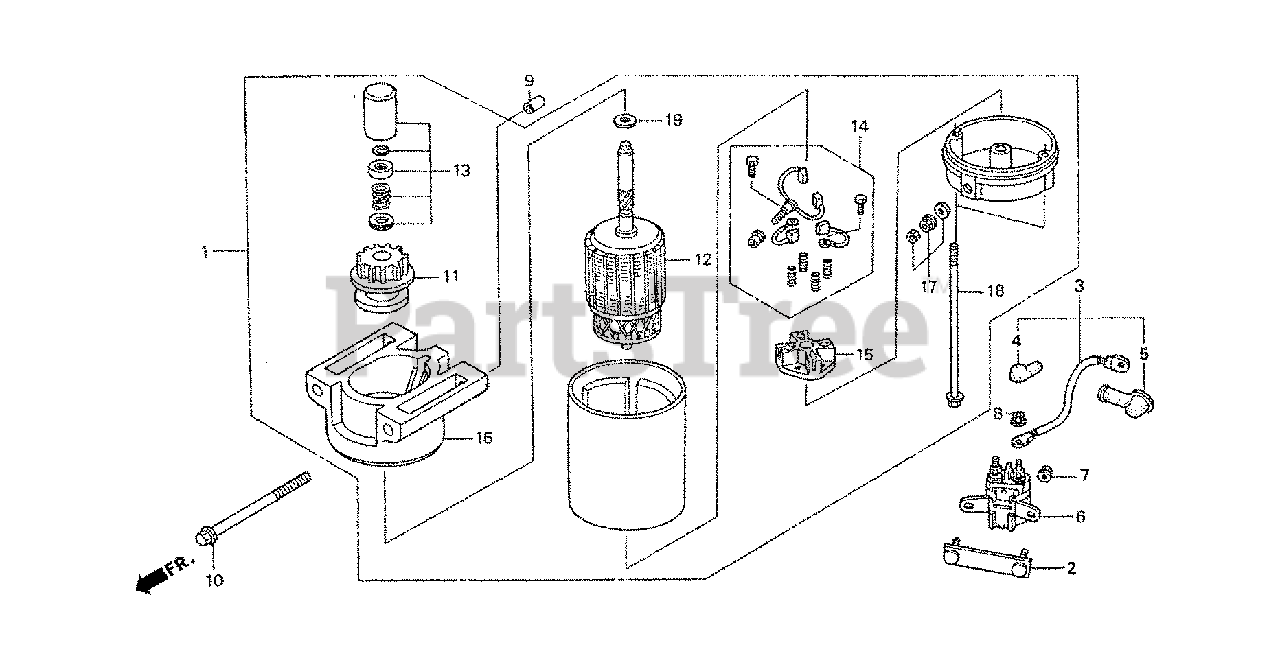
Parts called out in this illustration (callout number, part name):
1	MOTOR ASSY., STARTER
2	BRACKET, STARTER MAGNETIC SETTING
3	CABLE, MAGNET SWITCH
4	COVER A, MAGNETIC SWITCH
5	COVER, STARTER MOTOR TERMINAL
6	SWITCH ASSY., STARTER MAGNETIC
7	NUT, FLANGE (6MM)
8	NUT-WASHER (6MM)
9	PIN, DOWEL (10X12)
10	BOLT, FLANGE (8X110)
11	GEAR SET, PINION
12	ARMATURE
13	STOPPER SET, PINION
14	BRUSH SET
15	HOLDER, BRUSH
16	BRACKET, FR.
17	NUT SET, TERMINAL
18	BOLT, THROUGH
19	WASHER, THRUST
